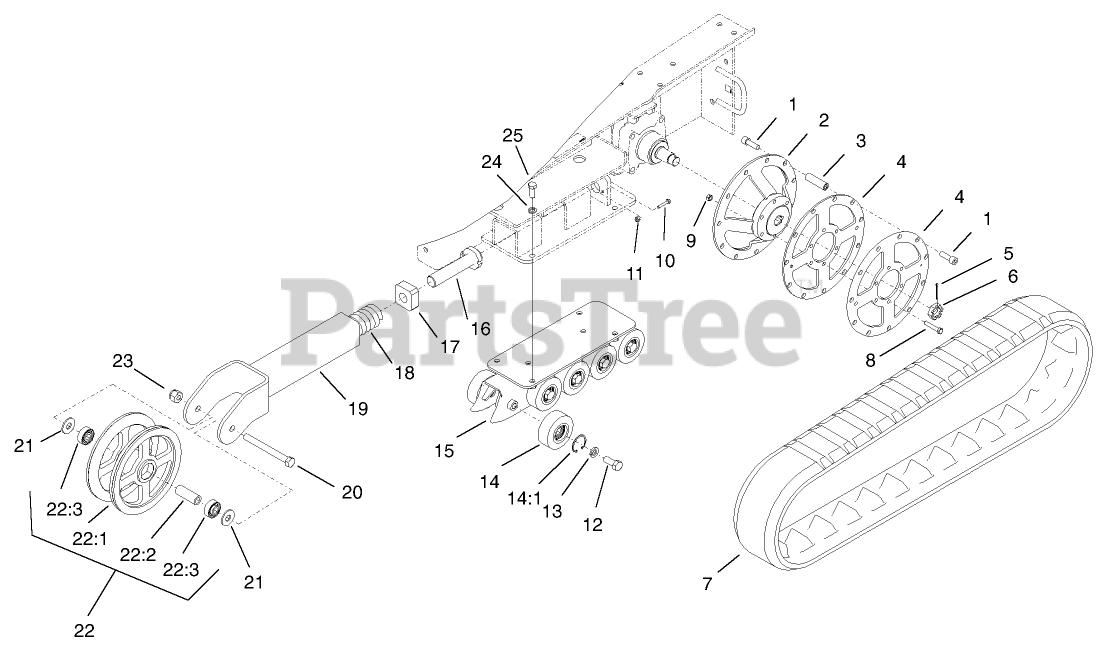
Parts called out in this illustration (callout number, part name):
1	SCREW-HSH
2	DRIVE WHEEL ASM
3	SPACER-WHEEL, DRIVE
4	PLATE-WHEEL, DRIVE
5	PIN-COTTER
7	TRACK
8	SCREW-HH
9	NUT-LOCK, SIDE
10	SCREW-HH
11	NUT-LOCK, NI
12	SCREW-HH
13	WASHER-LOCK
14	BOGGY WHEEL ASM
14:1	RING-RETAINING
15	TRACK GUIDE ASM
16	BOLT-TENSIONER
17	BLOCK-TENSIONER
18	SPRING-COMPRESSION
19	TENSIONER ARM ASM
20	SCREW-HH
21	WASHER-FLAT
22	TENSIONER WHEEL ASM
22:1	TENSIONER WHEEL ASM
22:2	SPACER-WHEEL, TENSIONER
22:3	BEARING
23	NUT-HEX
24	WASHER-LOCK
25	SCREW-HH
